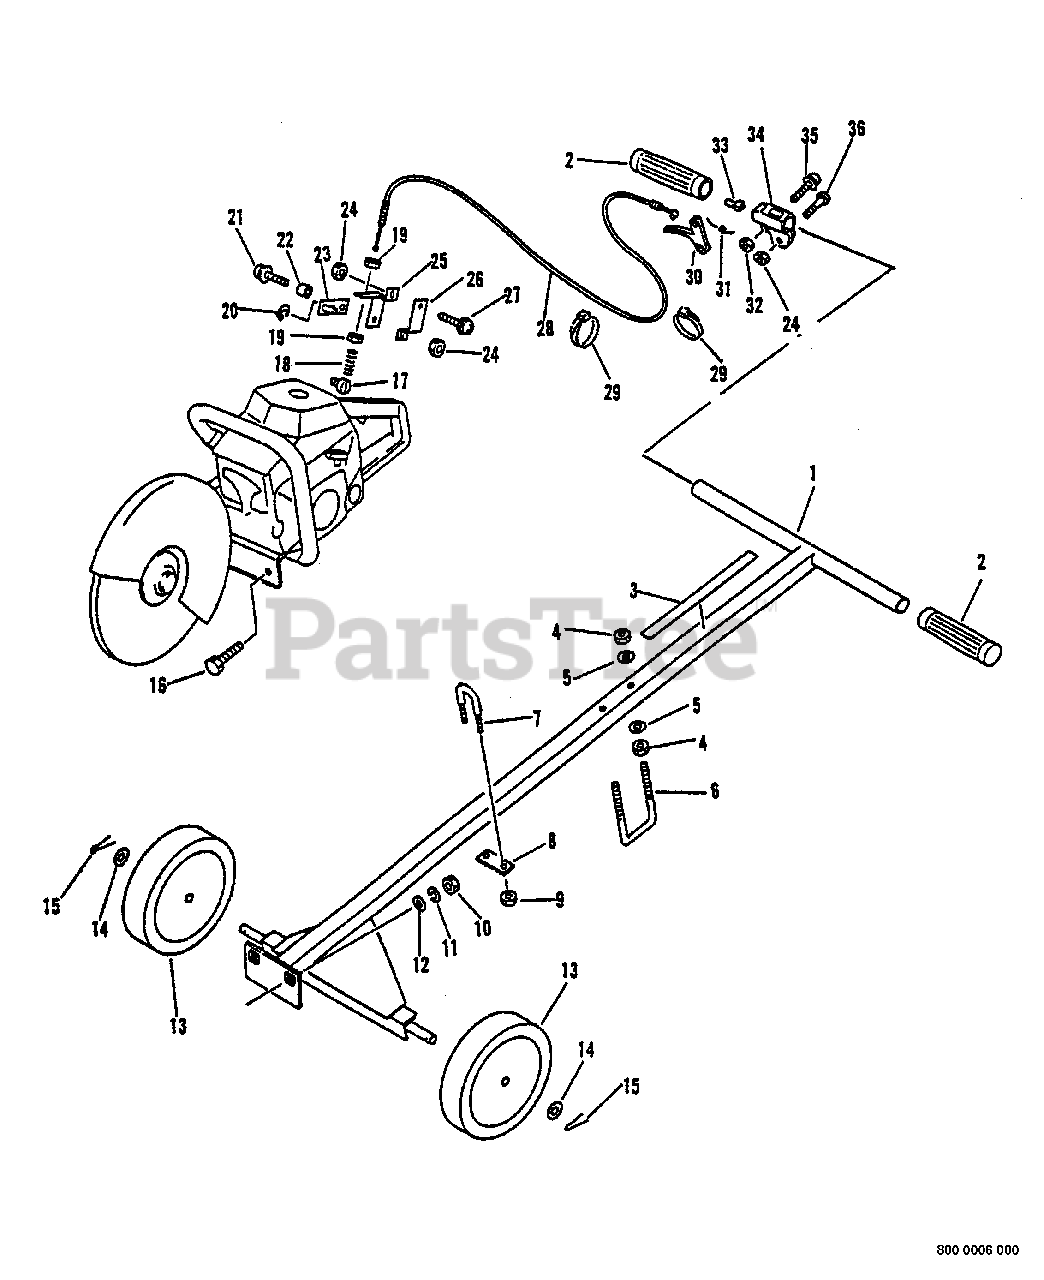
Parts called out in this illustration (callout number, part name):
1	CART
2	GRIP, HANDLE
3	LABEL - CAUTION
4	NUT - 3/8-16
5	WASHER - 3/8"
6	SQUARE BEND U-BOLT, LEG WIDTH 2", LENGTH 5"
7	U-BOLT, 1" PIPE, 1/4- 20 THREAD
8	PLATE
9	NUT - 1/4-20
10	NUT - 5/16-18
11	LOCKWASHER - 5/16"
12	WASHER - 5/16"
13	WHEEL
14	WASHER - 1/2"
15	PIN, SPLIT - 2X22
16	SCREW - 5/16-18 X 1"
18	SPRING, TRIGGER
20	RING, RETAINING - 4
21	SCREW - 5X22
23	TRIGGER, THROTTLE
24	LOCKNUT - 5
25	BRACKET
26	TRIGGER, MOUNTING BRACKET
27	SCREW - 5X16
28	CABLE, THROTTLE
29	TIE, CABLE
30	TRIGGER, THROTTLE
31	SPRING, TRIGGER
33	GUIDE, CABLE
34	BRACKET, TRIGGER
35	SCREW - 5X35
36	SCREW - 5X30
